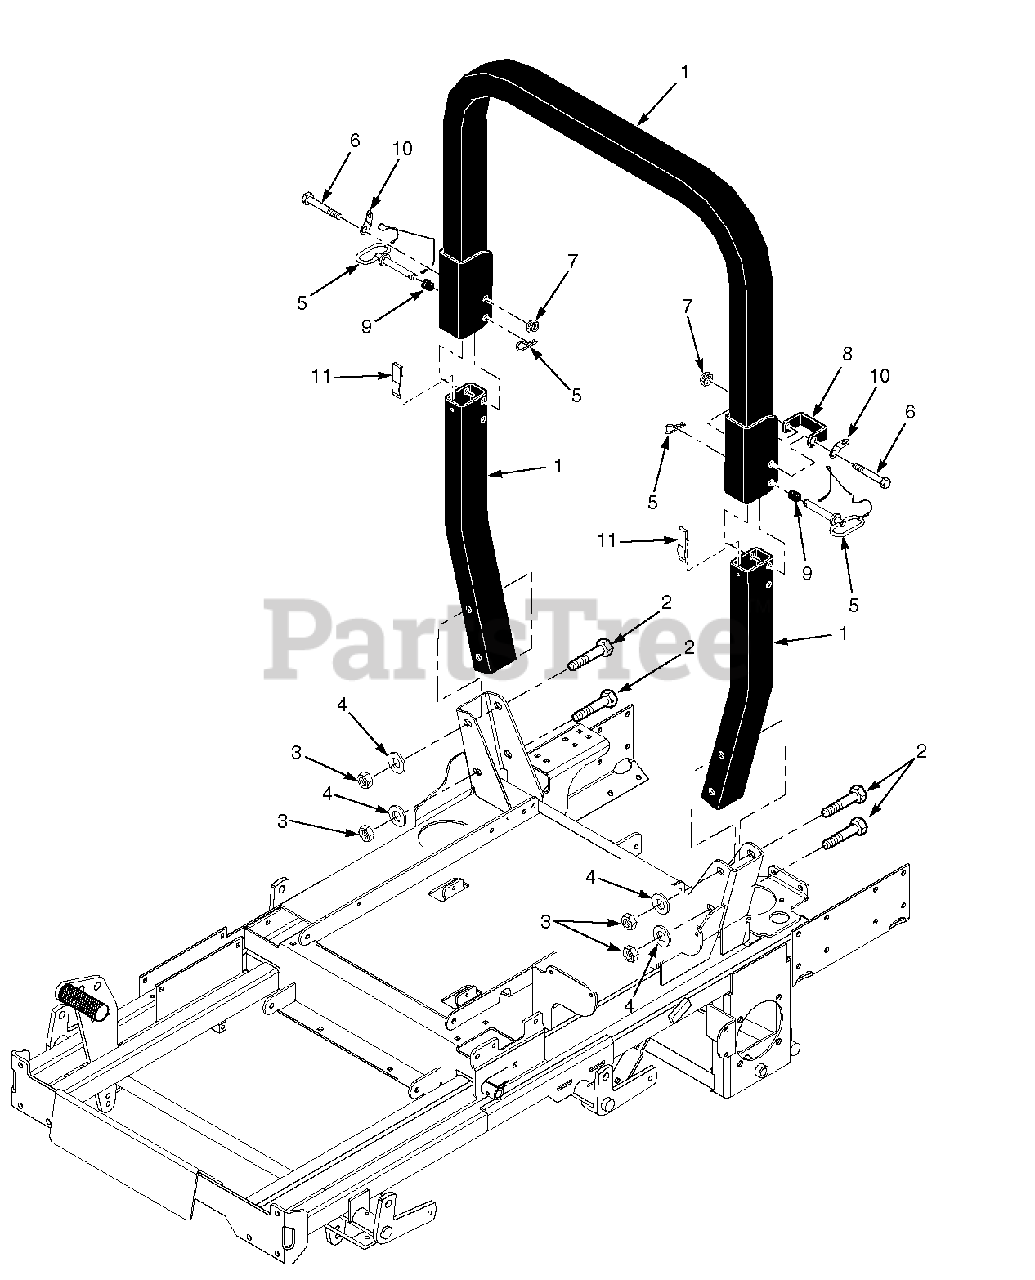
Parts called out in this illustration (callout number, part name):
1	STT, ROPS
2	Bolt, Hex Head 1/2-13 x 4"
3	Nut, Center Lock 1/2-13
4	Flatwasher, 1/2-.562 x 1.375 x .109
5	Pin Assembly
6	Bolt, Hex Head 1/2-13 x 3-3/4"
7	Nut, Center Lock 1/2-13
8	Stop Bracket, ROPS
9	Spring, ROPS
10	Clip, ROPS
11	Spring Clip, ROPS
